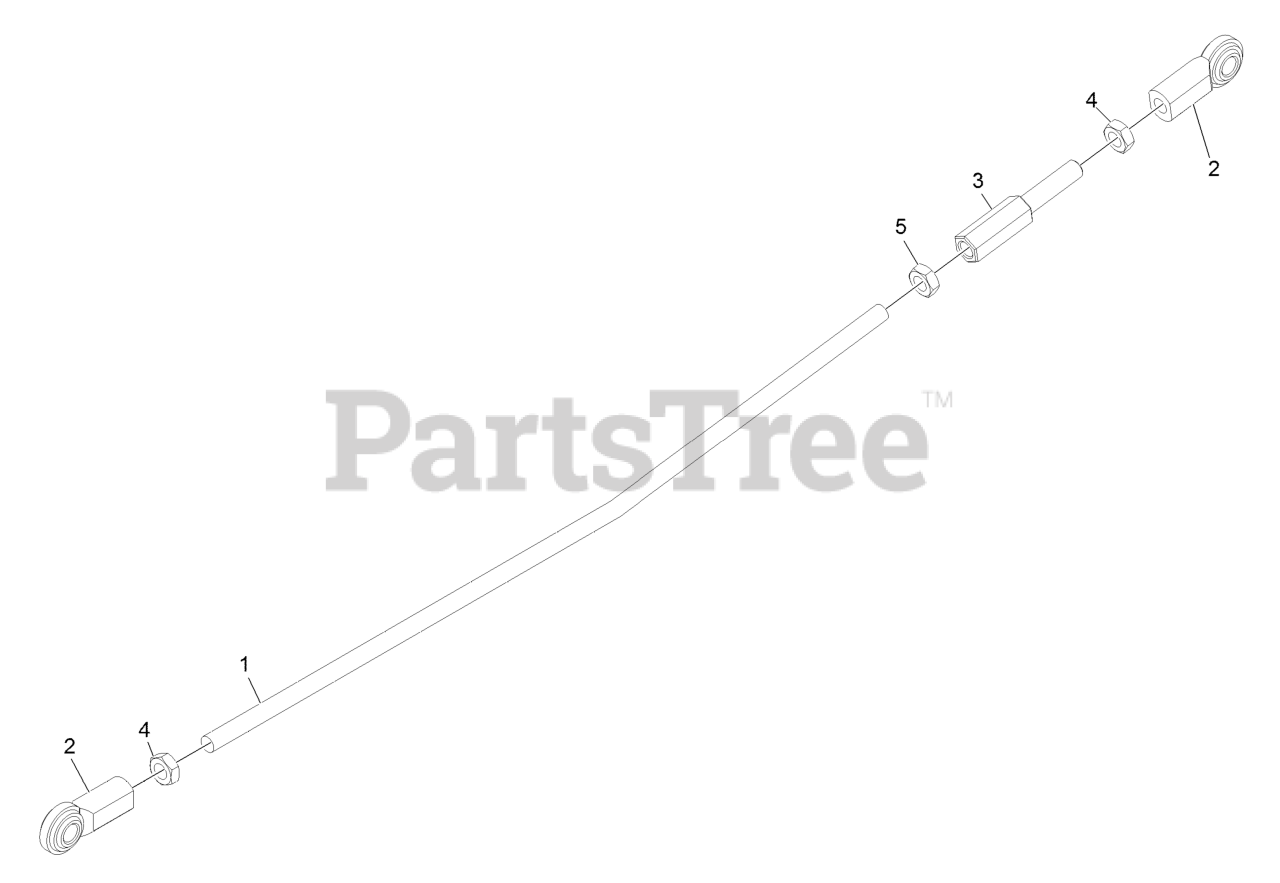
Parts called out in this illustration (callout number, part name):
1	LINK-LOWER, MOTION CONTRO
2	JOINT-BALL, END
3	ROD-ADJUSTMENT
4	NUT-HJ
5	NUT-HEX JAM, LH
